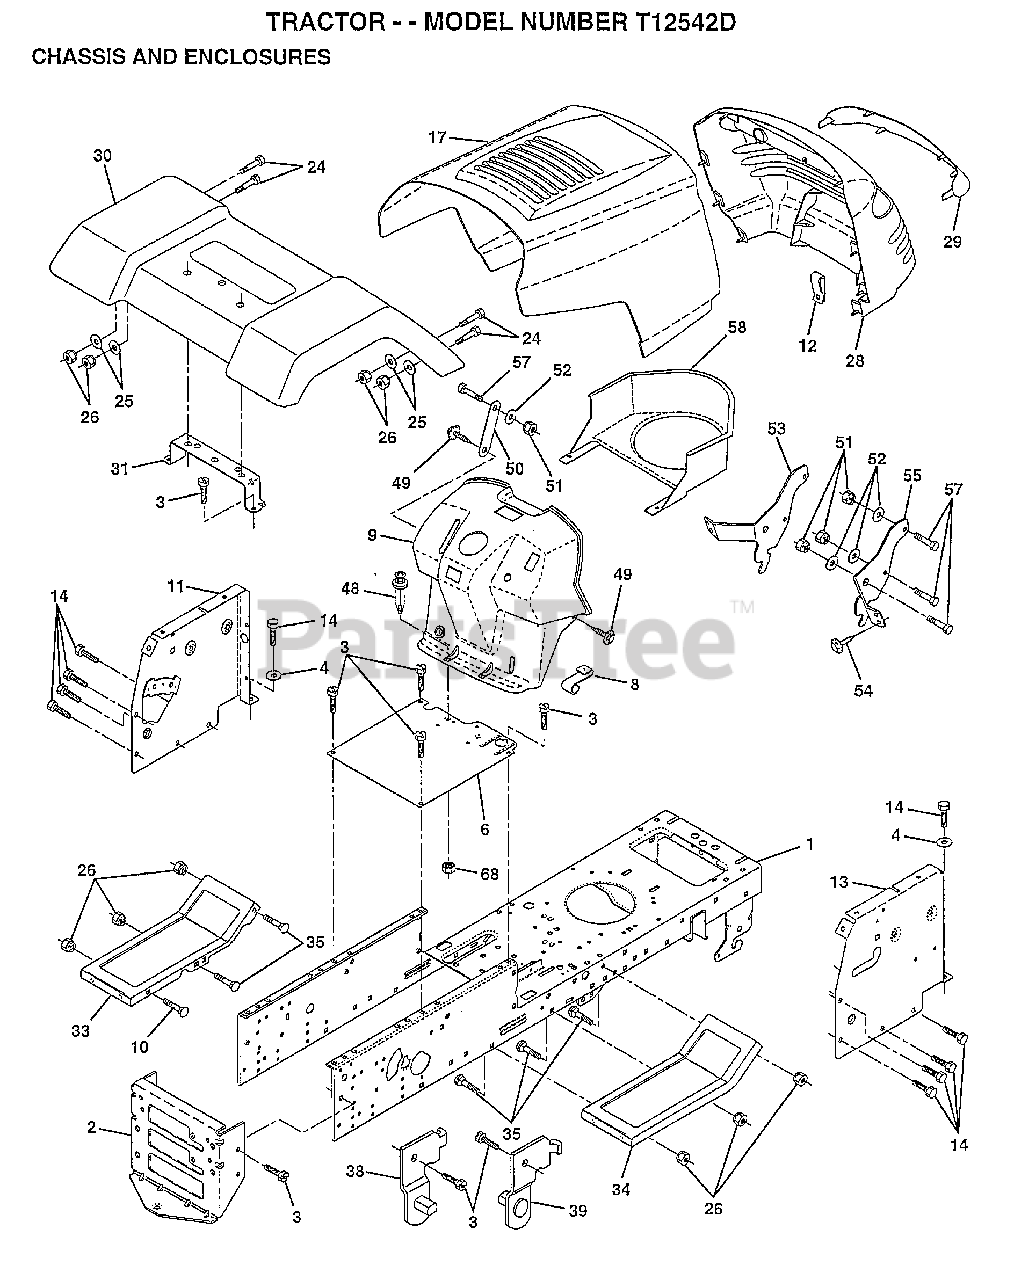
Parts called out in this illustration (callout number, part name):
1	CHASSIS WLDMT 11G
3	SCREW
4	WASHER
8	"CLIP,INSULATOR"
11	PANEL.DASH.LH.
12	CLIP.TINNERMAN
14	SCREW LT
24	BOLT
25	WASHER
26	NUT
29	LENS GRILLE
31	BRKT FENDER
33	FOOTREST.LH.PERF.
34	FOOTREST.RH.PERF.
35	BOLT
38	BRACKET ASM LH
39	BRACKET ASM RH
48	RIVET.PUSH.PLATE
49	SCREW HEX CRT
50	BRACE SUPT DASH
51	NUT
52	WASHER
53	BRACKET.GRILLE.LH
55	BRACKET.GRILLE.RH
58	AIR DUCT
68	NUT
